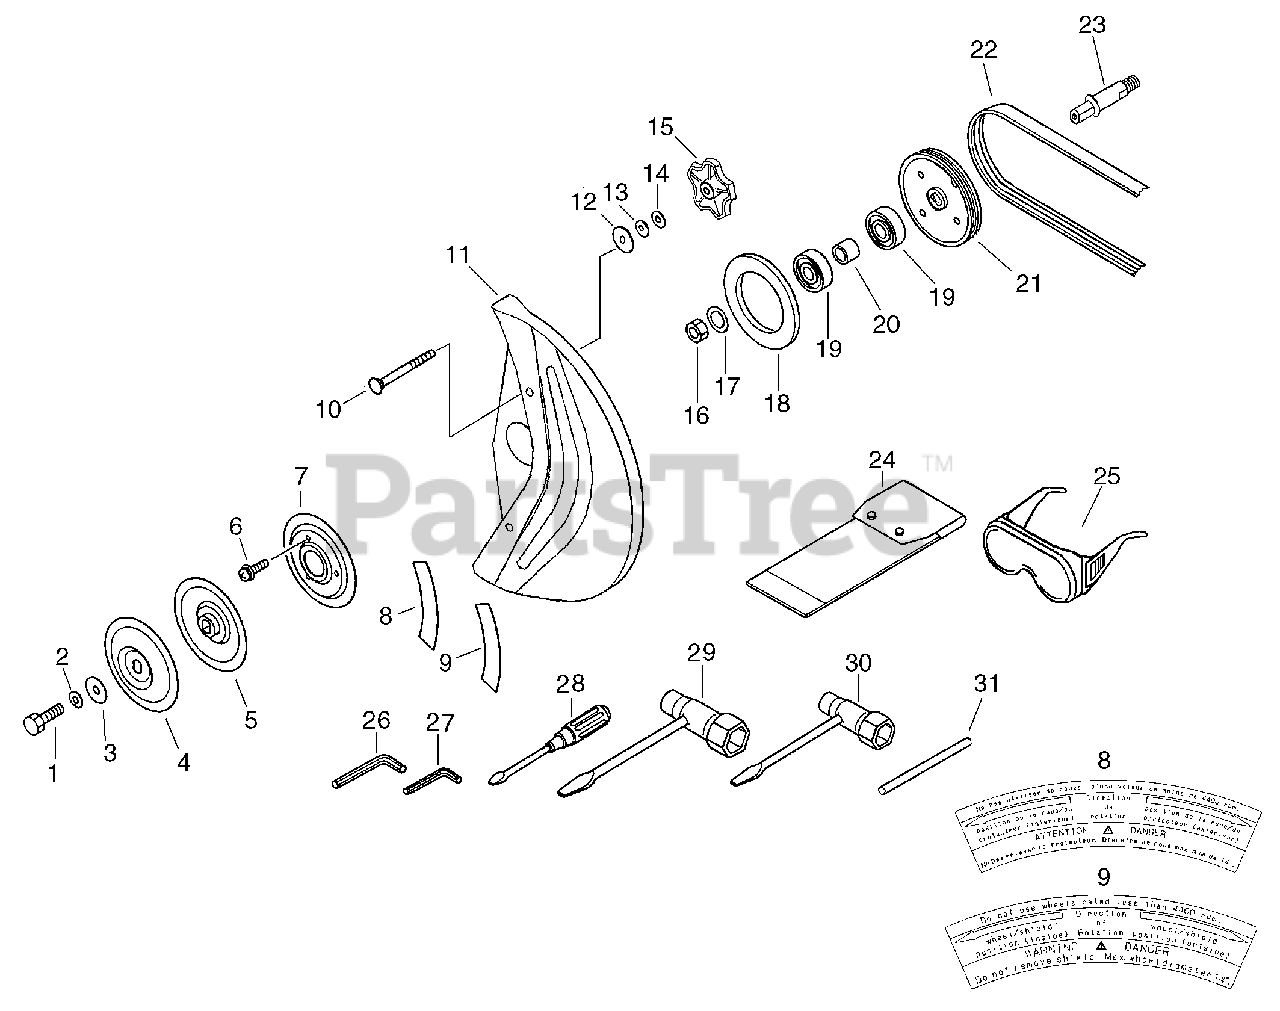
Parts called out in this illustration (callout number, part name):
2	LOCKWASHER - 10
4	FLANGE, CUTTER
5	FLANGE, CUTTER
6	SCREW - 4X10
7	PLATE, CUTTER COVER
9	LABEL - CAUTION
10	BOLT - 8
11	COVER, CUTTER
12	WASHER - 8
13	WASHER - 8
14	LOCKWASHER - 8
15	KNOB, FASTENER
16	NUT - 10
17	WASHER - 10
19	BEARING, BALL - 6202
21	PULLEY
22	BELT
23	SHAFT, CUTTER
24	BAG, TOOL
25	GOGGLES
26	HEX KEY - 4mm
27	HEX KEY - 3mm
28	SCREWDRIVER
29	T-WRENCH - 17X19mm
30	T-WRENCH
31	LOCKING TOOL
